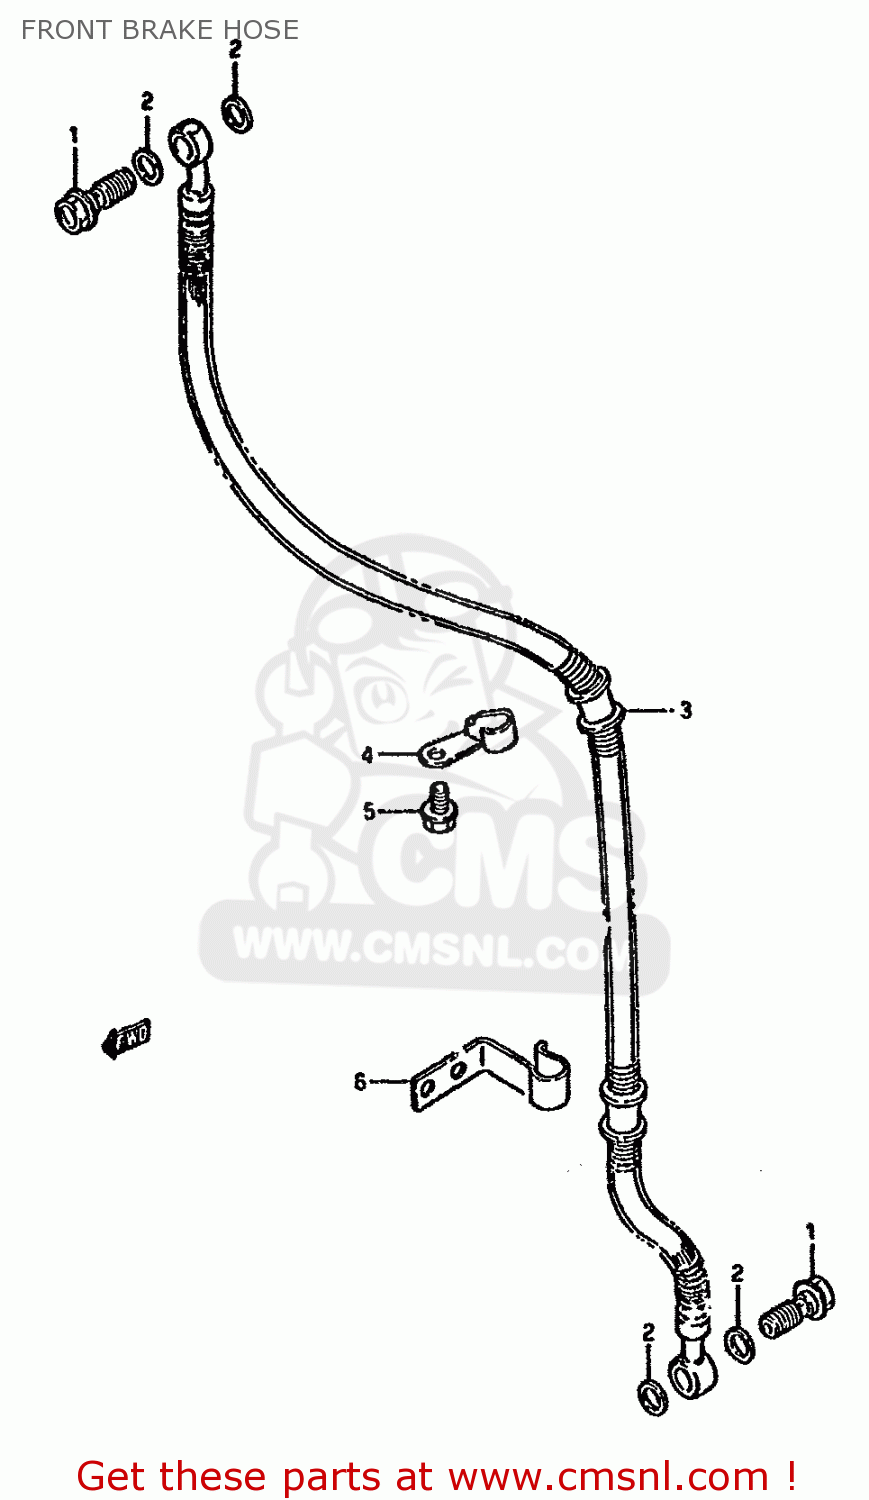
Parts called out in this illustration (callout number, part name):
1	BOLT UNION
2	WASHER(10X15X1.5)
3	HOSE,FR BRAKE
4	GUIDE,BRAKE HOSE NO.1
5	BOLT
6	GUIDE,BRAKE HOSE NO.2
